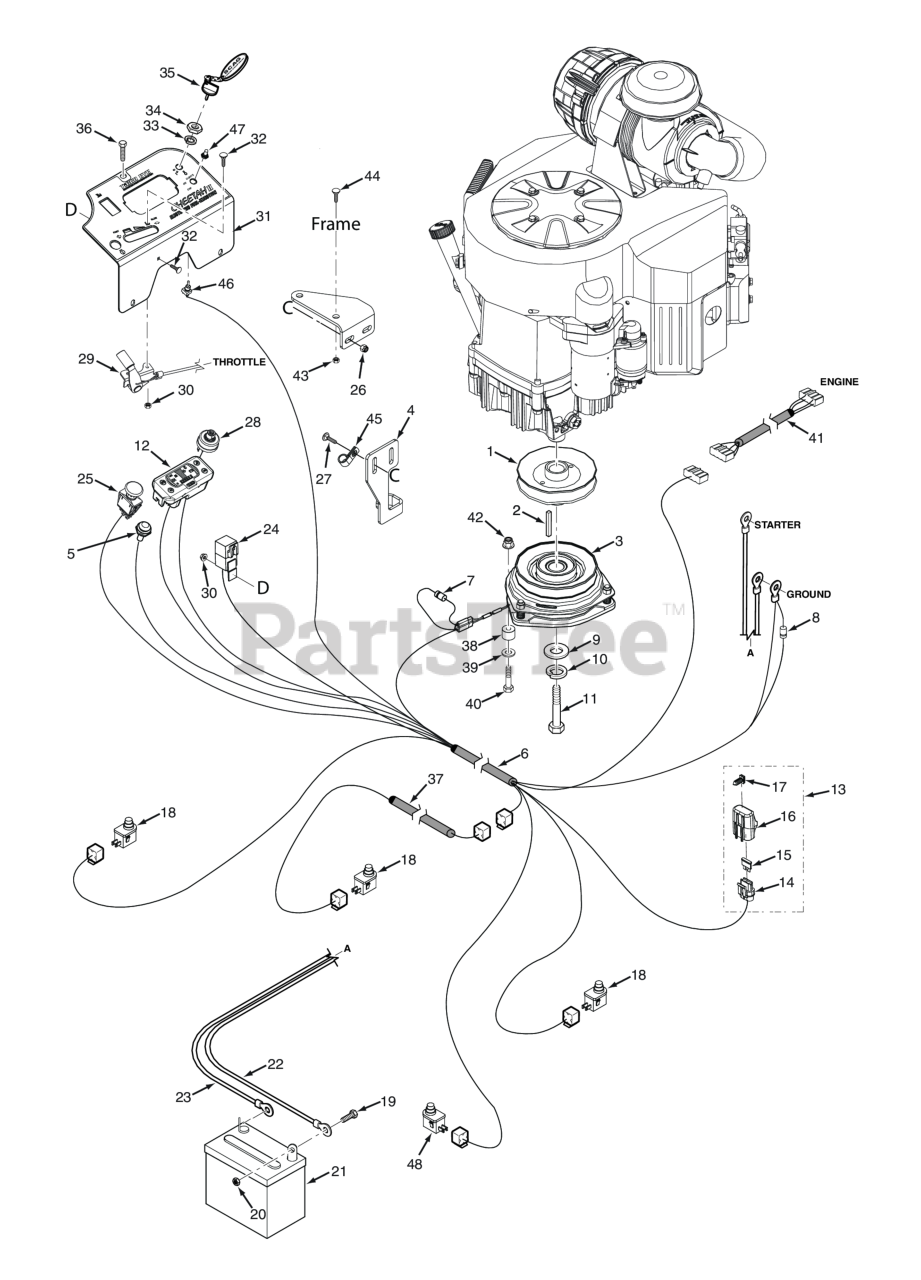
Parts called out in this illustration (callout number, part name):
1	Pulley, 5.80" Dia. - 1.125 Bore
2	Key, 1/4 x 1/4 x 3-1/4�
3	Electric Clutch w/Tag - GT-5 (ECV860, ECV940)
4	Bracket, Anti-Rotation
5	Indicator Light, Glow Plugs (Includes Mounting Hardware)
6	Wire Harness, SCZII-EFI
7	Diode, 600V 6 Amp
8	Decal, Forward Speed Selector
9	Flatwasher, 7/16-.469 x 1.75 x .25 (48, 52)
10	Lockwasher, 7/16� Spring
11	Bolt, Hex Head 7/16-20 x 2-1/4" w/Patch (Kawasaki)
12	Tiger Eye, Cluster Gauge
13	Single Fuse Assy., Excluding Fuse
14	Fuse Holder Assembly
15	FUSE, 20 AMP BLADE TYPE AUTOMOTIVE
16	Cover, Sealed Single
17	Clip, Fuse Holder
18	Switch, Interlock, Normally Open
19	Bolt, Hex Head 1/4-20 x .5" Battery, (Not Available Through Scag)
20	Nut, 1/4 - 20 Hex
21	Battery
22	Battery Cable, 18" Black (Kohler)
23	Battery Cable, 25" Red
24	Relay, 12V 40 AMP Standard
25	Switch, PTO - 10 Amp
26	Nut, Flange Head Elastic Stop 5/16-18
27	Bolt, Carriage 5/16-18x1" (large frame units only)
28	KEY SWITCH(INCLUDES MOUNTING HARDWARE)
29	Control Cable (Kawasaki FX921 Throttle & Choke Cable)
30	Nut, Elastic Stop #10-24
31	Instrument Panel w/Decal
32	Bolt, Carriage #10-24 x 1/2"
33	LOCK WASHER, 5/8" INTERNAL TOOTH
34	Nut, 5/8-32 Special
35	Key, Assembly w/Fob
36	CAP SCREW, 1/4-20 X 1/2" SERRATED FLANGE HEX
37	Wire Harness, Operator Platform -SCZ
38	Bushing, UHMW
39	Flatwasher, 5/16-.375 x .875 x .083 (35BV & 37BV-EFI)
40	Bolt, Hex Head 5/16-18 x 1-1/2" (Right Front Engine Mounting, Briggs and Kohler Only)
41	Wire Harness Adapter, Briggs & Stratton 37 BV-EFI
42	HEX NUT, ELASTIC STOP LOCK, 5/16-18
43	NUT, 3/8-16 SERRATED FLANGE HEX HEAD
44	Carriage Bolt, 3/8-16 x 1.0"
45	Clamp, Cable 1/2" I.D.
46	SWITCH, ON / OFF
47	BOOT, SWITCH
48	Switch, N/C
